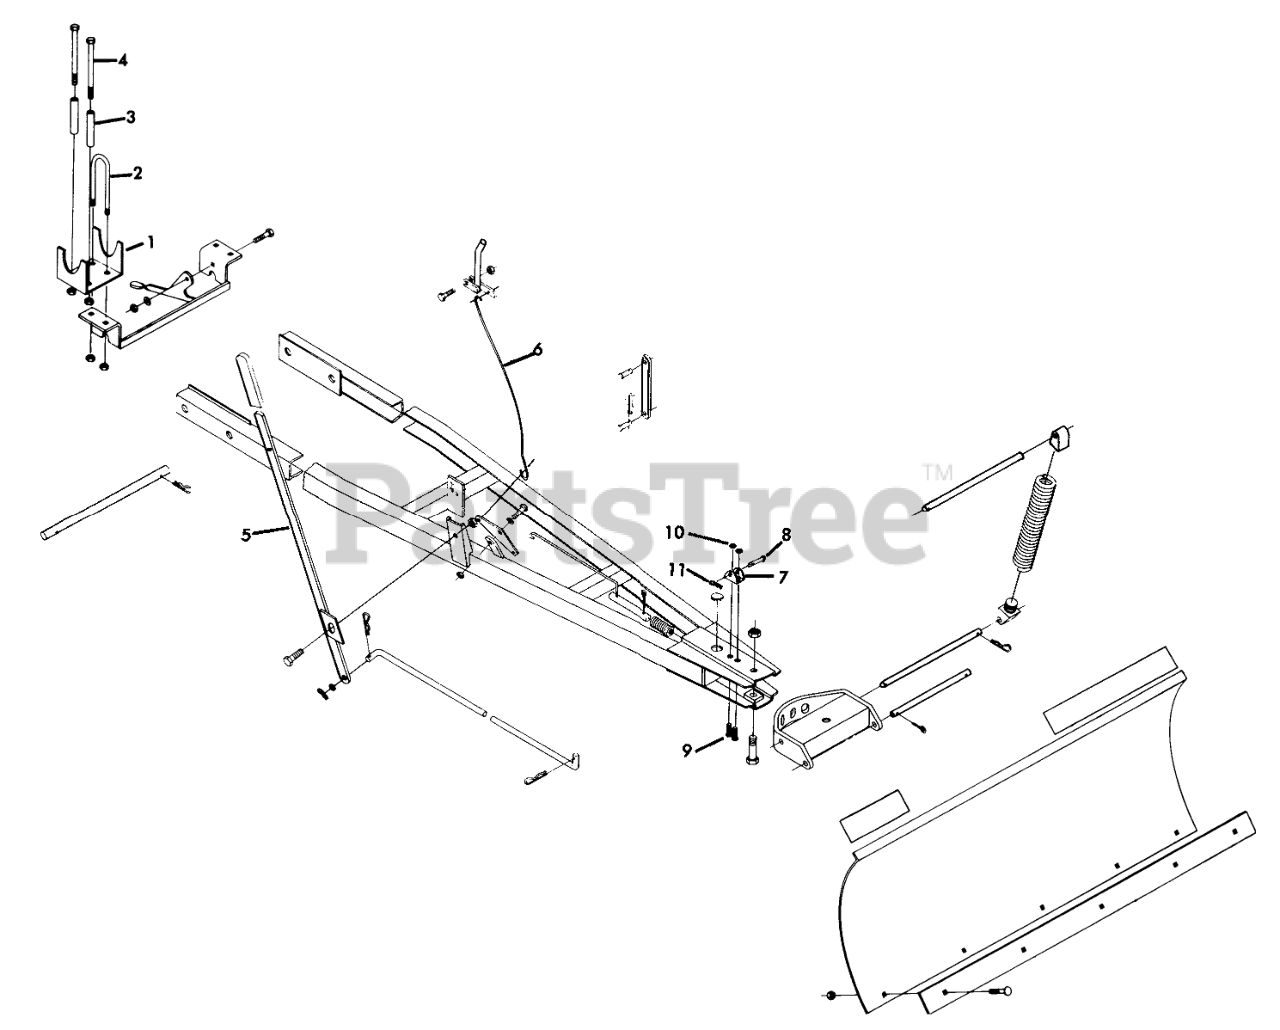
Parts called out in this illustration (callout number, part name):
1	Bracket
2	U-Bolt
3	Standoff
4	Hex Bolt
5	Index Lever
6	Upper Index Rod
6	Washer
7	Lift Clevis
8	Clevis Pin
9	Hex Bolt 1/4-20 x 3/4
10	Nut
11	Hairpin Cotter
